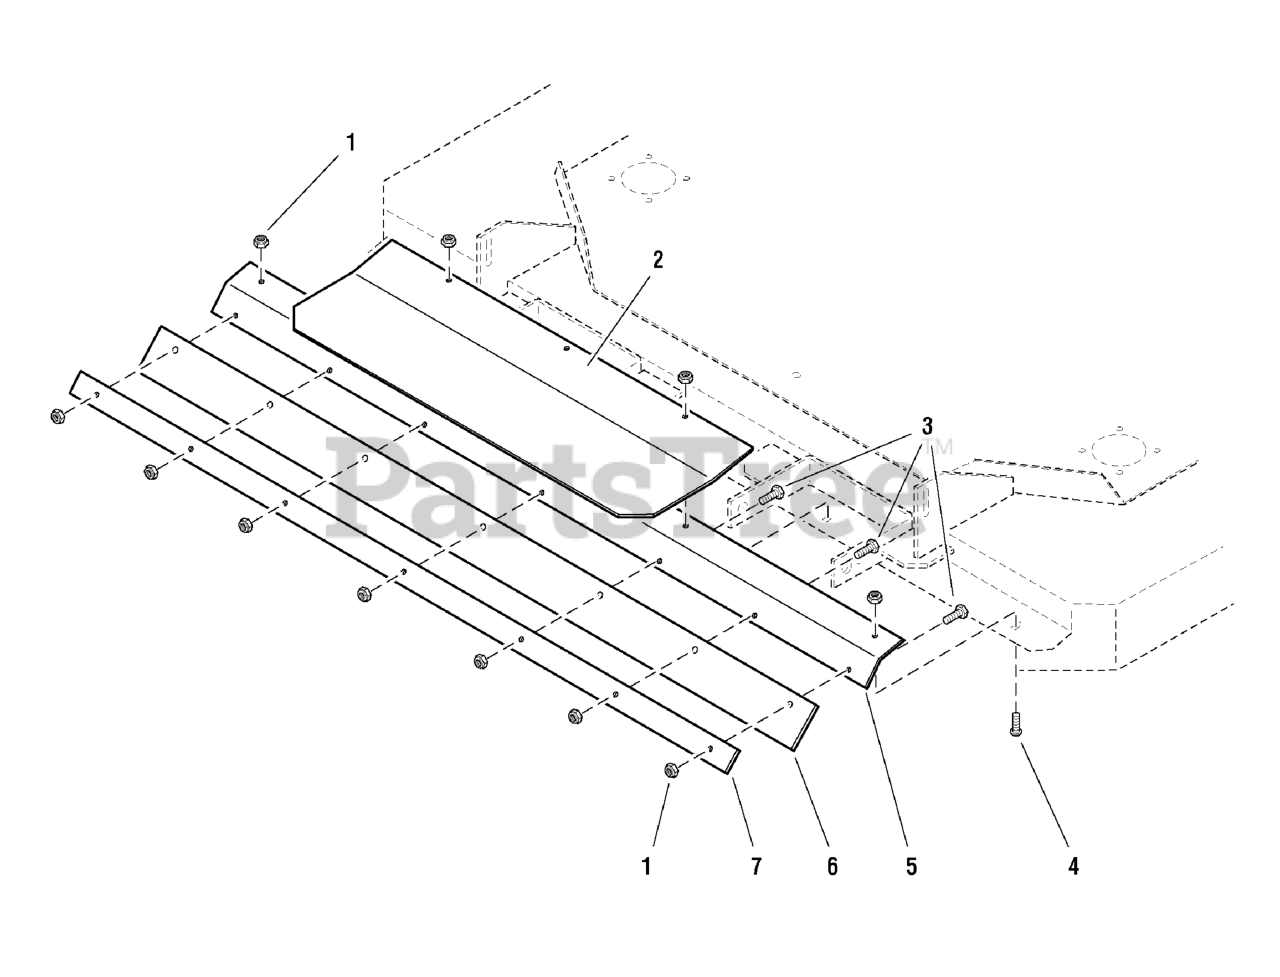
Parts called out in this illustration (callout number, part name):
1	NUT, 5/16-18 Hex Nylon Lock
3	BOLT, 5/16-18 X 1 GD5 YZ
4	CARRIAGE BOLT, 5/16-18 x 1
5	DEFECTOR MOUNT
6	RUBBER DEFLECTOR
7	RETAINING PLATE
